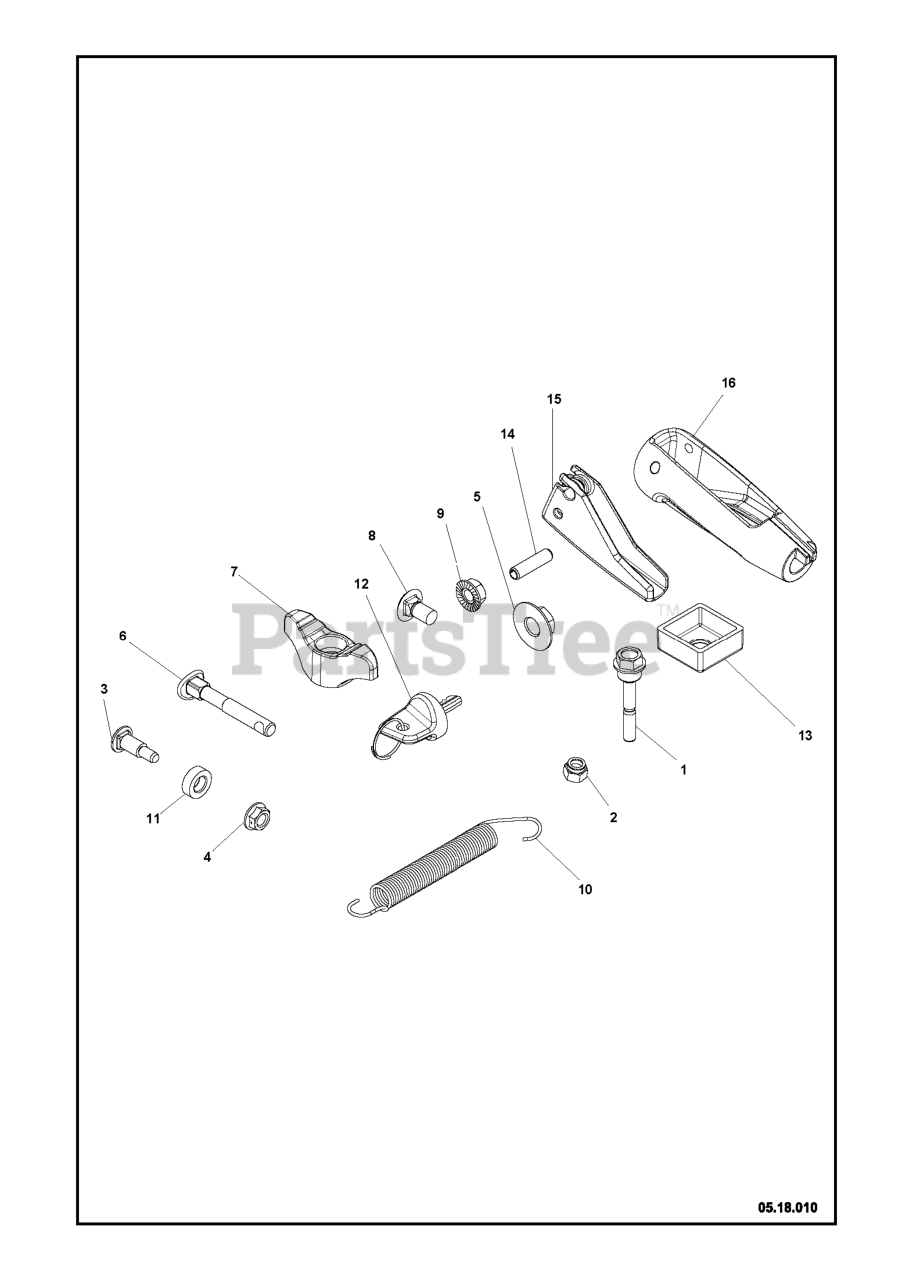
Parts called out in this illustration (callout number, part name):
1	BOLT SHEAR HX HD 1/4-20 CLEAR
2	NUT HEXAGON 1/4-20 ST ZPB
3	BOLT.CARR.W.3125 SHLDR..25-20
4	NUT.HEX.LRG.FLANGE.1/4-20.LOCK
5	NUT.HEX.FLANGE.LOCK BLK 3/8-16
6	BOLT.CARRIAGE.5/16-18 X 2.25
7	KNOB, DEFLECTOR
8	BOLT CAR BLK 5/16-18 X 5/8
9	LOCKNUT-FLANGE 5/16-18
10	SPRING.DEFLECTOR.REM.CHUTE
11	WASHER.NYLON.326 X.625 X.205
12	KEY IGNITION, WITH UMBRELLA
13	RETAINER CHUTE
14	PIN.ROLL.3/16 X 1"
